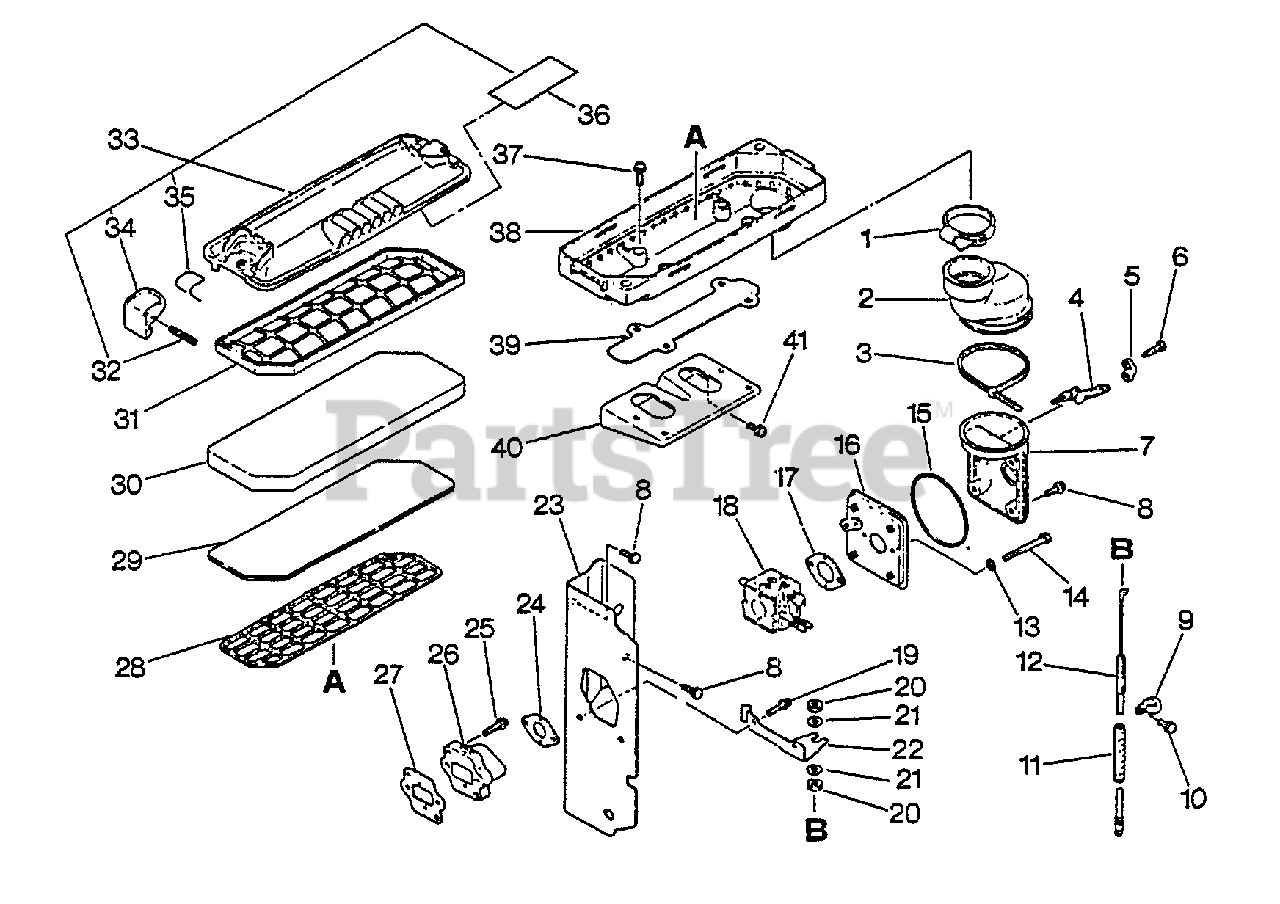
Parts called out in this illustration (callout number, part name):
1	CLAMP
2	ADAPTOR, INTAKE
4	ROD, CHOKE
5	HOLDER, CHOKE ROD
6	SCREW - 4X16
7	O-RING
8	SCREW - 4X10
10	SCREW - 5X10
11	WRAP, SPIRAL - 130mm
12	CABLE, THROTTLE
13	WASHER - 5
14	BOLT
15	O-RING
16	BRACKET, CARBURETOR
17	GASKET, INTAKE
18	CARBURETOR
19	SCREW - 4X12
21	WASHER - 6
23	INSULATOR
24	GASKET, INTAKE
25	SCREW - 5X25
26	INSULATOR, INTAKE
27	GASKET, INTAKE
28	RETAINER, AIR FILTER
29	FILTER, AIR
30	FILTER, AIR
31	RETAINER, AIR FILTER
32	PIN - SPRING -- 3X25
33	AIR FILTER COVER ASSY
34	LATCH
35	HOOK, SPRING
36	LABEL - CLEANER
37	SCREW - 4X12
38	CASE, AIR FILTER
40	BRACKET, AIR CLEANER
41	SCREW - 5X14
